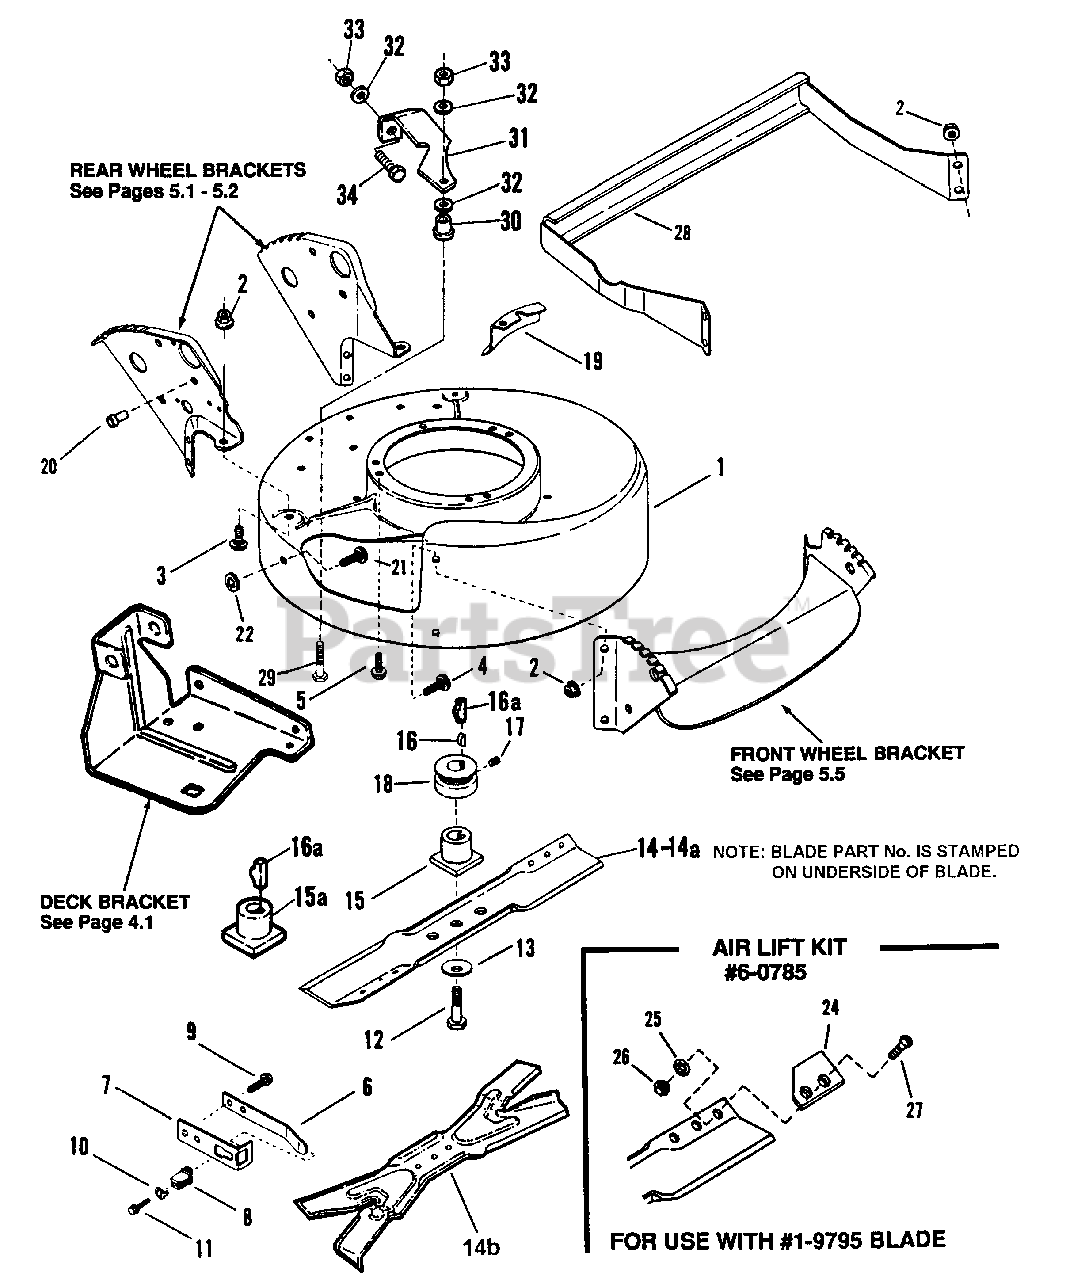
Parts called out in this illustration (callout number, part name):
1	DECK, Mower
2	NUT, 5/16-18 Hex Flange Lock, Grade 5
3	BOLT, 5/16-18 x 1/2" Short Neck Carriage, Grade 5
4	BOLT, 5/16-18 x 1-1/8" Short Neck Carriage, Grade 5
5	SCREW, 3/8-16 x 1" Hex Washer Self-Tap
6	SPRING, Wheel Bracket Type Interlock
7	BRACKET, Wheel Bracket Type Interlock
8	INSULATOR, Interlock
9	SCREW, 1/4-20 x 1/2" Hex Washer Self-Tap
10	WASHER, #8 Tab Internal Tooth Lock
11	SCREW, #8-18 x 3/4" Hex Head Machine
12	SCREW, 3/8-24 x 2" Hex Head Cap, Grade 5
13	WASHER, Cone
14	BLADE, Cutter, 20.75"
14A	BLADE, Cutter, 20.73"
14B	BLADE, Cutter, 20.73" Quad Edge
15	HUB, Blade Drive 25mm
15A	HUB, Blade Drive 7/8"
16	KEY, Woodruff #605 (Briggs)
16A	KEY, Woodruff Hi-Pro
17	SCREW, 5/16-18 x 5/16" Hex Socket Set
18	PULLEY, Engine- 25mm x 2-1/8" Outside Diameter
18	PULLEY, Engine- .875 x 2-1/4" Outside Diameter
19	SHIELD, Belt Opening Cover
20	BUSHING, Interlock Wire
21	BOLT, 5/16-18 x 3/4" Short Neck Carriage, Grade 5
22	RETAINER, 5/16" Bolt
24	LIFT, Air
25	WASHER, 5/16 Internal Tooth Lock
26	NUT, 5/16-24 Hex
27	SCREW, 5/16-24 x 21/32" Oval Head Machine
28	STRUCTURE, Fender
29	BOLT, 5/16-18 x 2-1/4" Hex Flange Lock
30	BUSHING
31	COVER, Belt
32	WASHER, 5/16" Split Lock
33	NUT, 5/16-18 Hex
34	SCREW, 5/16-18 x 1/2" Hex Head Cap, Grade 5
